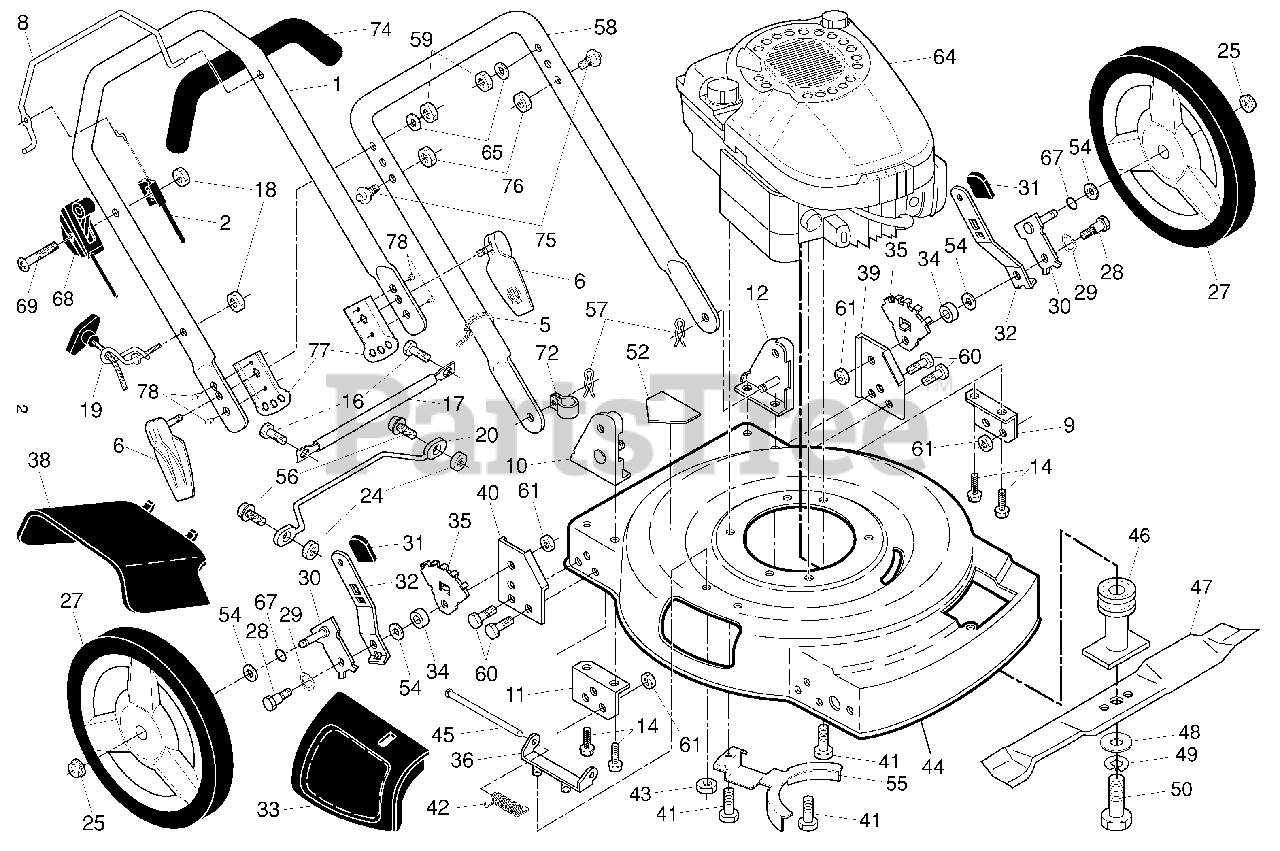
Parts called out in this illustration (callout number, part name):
1	Upper Handle
2	Engine Zone Control Cable
5	Wire Tie
6	Handle Knob
8	Control Bar
9	Support Bracket, Handle, LH
10	Handle Bracket Assembly, RH
11	Support Bracket, Handle, RH
12	Handle Bracket Assembly, LH
14	Screw, Thread Cutting 5/16-18 x 3/4
16	Screw, Tapping, Hex Head 1/4-20 x 1/2
17	Rod, Support
18	Locknut, Keps
19	Rope Guide
20	Foot Guard
25	Locknut, Hex 3/18-16
27	Wheel & Tire Assembly, Rear
28	Shoulder Bolt
29	Curved Washer
30	Axle Arm Assembly
31	Knob, Selector
32	Spring, Selector
33	Discharge Guard
35	Bracket, Wheel Adjuster
36	Bracket, Housing
38	Deflector, Discharge
39	Support Bracket, LH
40	Support Bracket, RH
41	Screw, Hex Head, Threaded, Rolled 3/8-16 x 1-1/8
42	Spring, Torsion
43	Locknut, Hex
44	Kit, Mower Housing
45	Rod, Hinge
46	Blade Adapter / Pulley
47	Blade, 22"
48	Washer, Hardened
49	Washer, Lock, Helical
50	Screw, Hex Head 3/8-24 x 1-3/8 (Grade 8)
52	Decal, Danger
54	Washer, Flat 3/8
55	Belt Keeper
56	Screw, Hex Washer Head #10-24 x 1/2
57	Hairpin Cotter
58	Lower Handle
59	Locknut, Hex 1/4-20
60	Bolt, Hex Head 3/8-16 x 3/4
61	Locknut, Hex
64	Engine, Briggs & Stratton, Model Number 124T02- 1254-EA (Order parts from engine manufacturer)
65	Washer, Flat
68	Control Throttle
69	Screw Hex 1/4 x 20 x 2.17
72	Clip, Cable
74	Handle Grip
76	Nut, Hex
77	Bracket, Quick-Release
